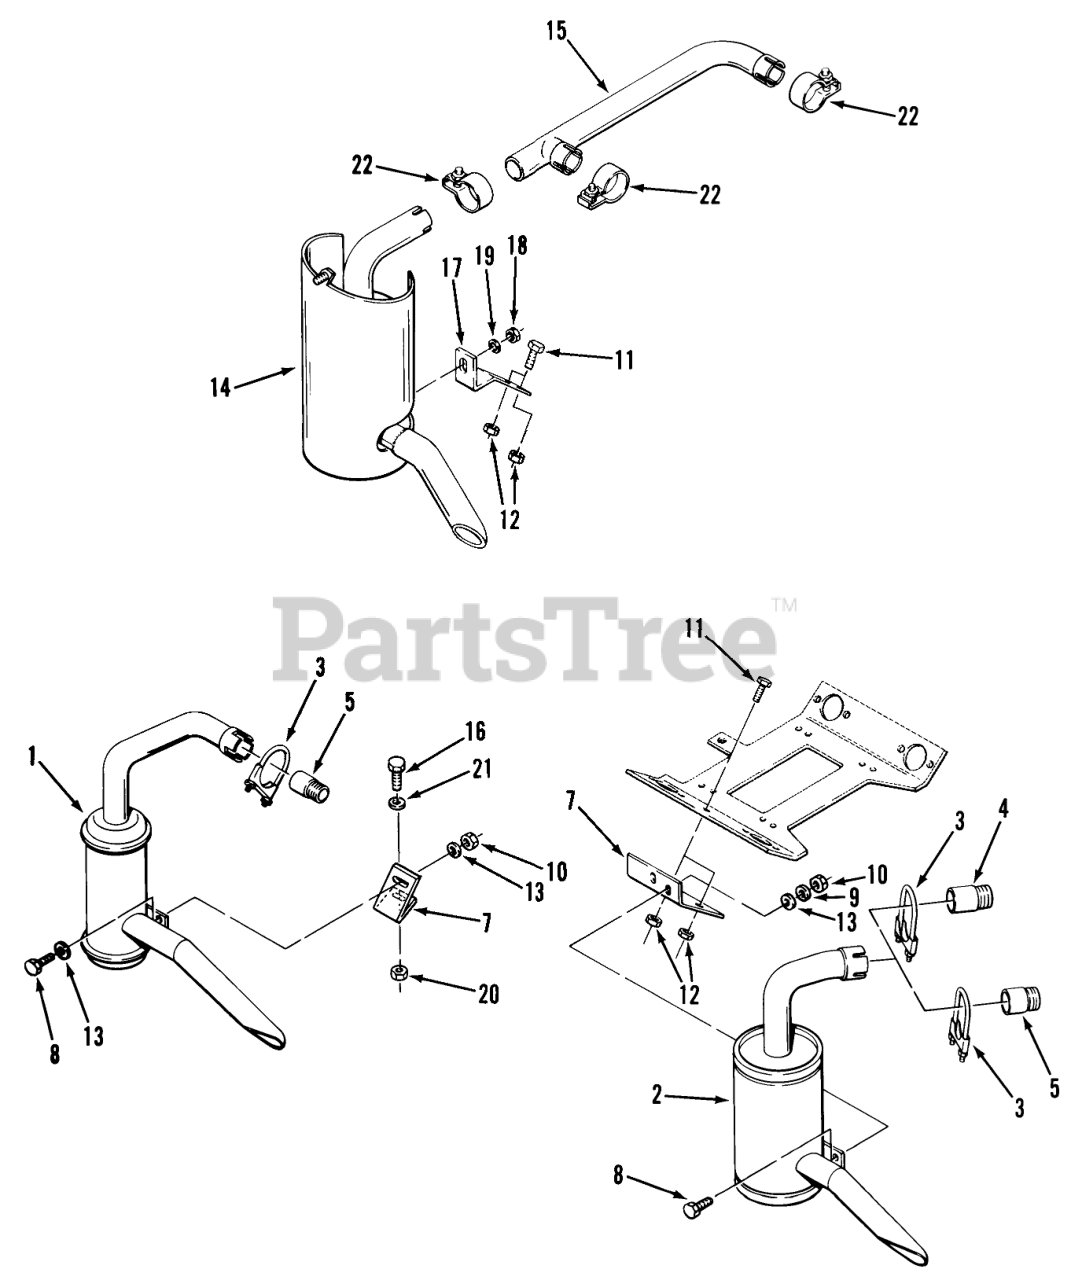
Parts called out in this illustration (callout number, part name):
1	ASSY-MUFFLER
2	MUFFLER ASSEMBLY
3	ASSY-MUFFLER CLAMP
4	NIPPLE
5	NIPPLE- 1X2 SPECIAL
7	BRACKET-MUFFLER MTG
7	Muffler Mounting Bracket C-85 Only
8	H H C S
8	Bolt
9	Washer
10	Nut
11	Bolt
12	Nut
14	Muffler C-175 Twin Only
15	MANIFOLD-EXHAUST
16	BOLT
17	BRACKET-MUFFLER
18	Nut
19	LOCKWASHER
20	Nut
21	Washer
22	CLAMP-MUFFLER
